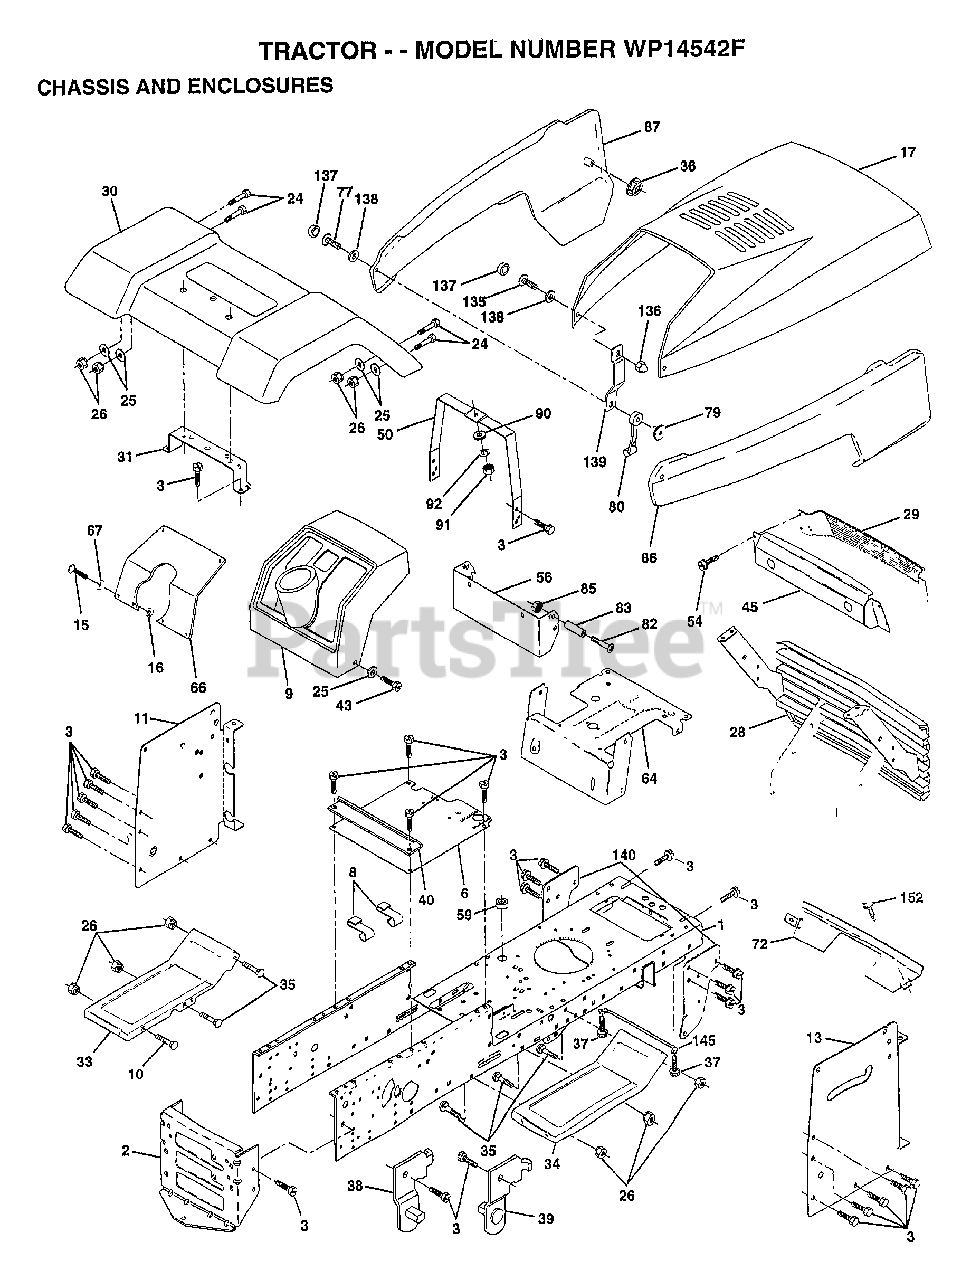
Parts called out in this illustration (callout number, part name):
1	CHASSIS.STAMPING
3	SCREW
6	SADDLE
8	"CLIP,INSULATOR"
9	DASHBOARD BLACK
11	PANEL.DASH.LH.
13	PANEL.DASH.RH.
15	SCREW
24	BOLT
25	WASHER
26	NUT
28	GRILLE ASM PNT
29	LENS.BAR.CLEAR
30	FENDER.LTST.WLDMNT.W/SHIFT
31	BRACKET SUPT FEND
33	FOOTREST.LH.LT/GT
34	FOOTREST.RH.LT/GT
35	BOLT
36	PAL NUT LT
37	SCREW LT
38	BRACKET ASM LH
39	BRACKET ASM RH
40	SPACER FENDER LT
43	SCREW GTV
45	BEZEL.ASM.
50	DASH.SUPT.YP/HUSQ
54	SCREW.HEX.WS.HD
56	EXT DASH LTYT
64	DASH.LOWER.LT
67	WASHER
72	STRAP.GRILLE.PNT.
77	SCREW
79	WELDNUT
80	HOOD LATCH T
82	SCREW
83	SPACER LT
87	"PANEL SIDE,LH"
90	WASHER PM
92	LOCKWASHER
135	SCREW.10-24X3/8.
136	ACORN NUT RB
137	SNAP CAP LT
138	WASHER LT
139	BKT.SPT.HOOD/PANL
140	BRKT SUSPENSION
145	"ROD POVOT,CHASSIS"
152	SCREW
